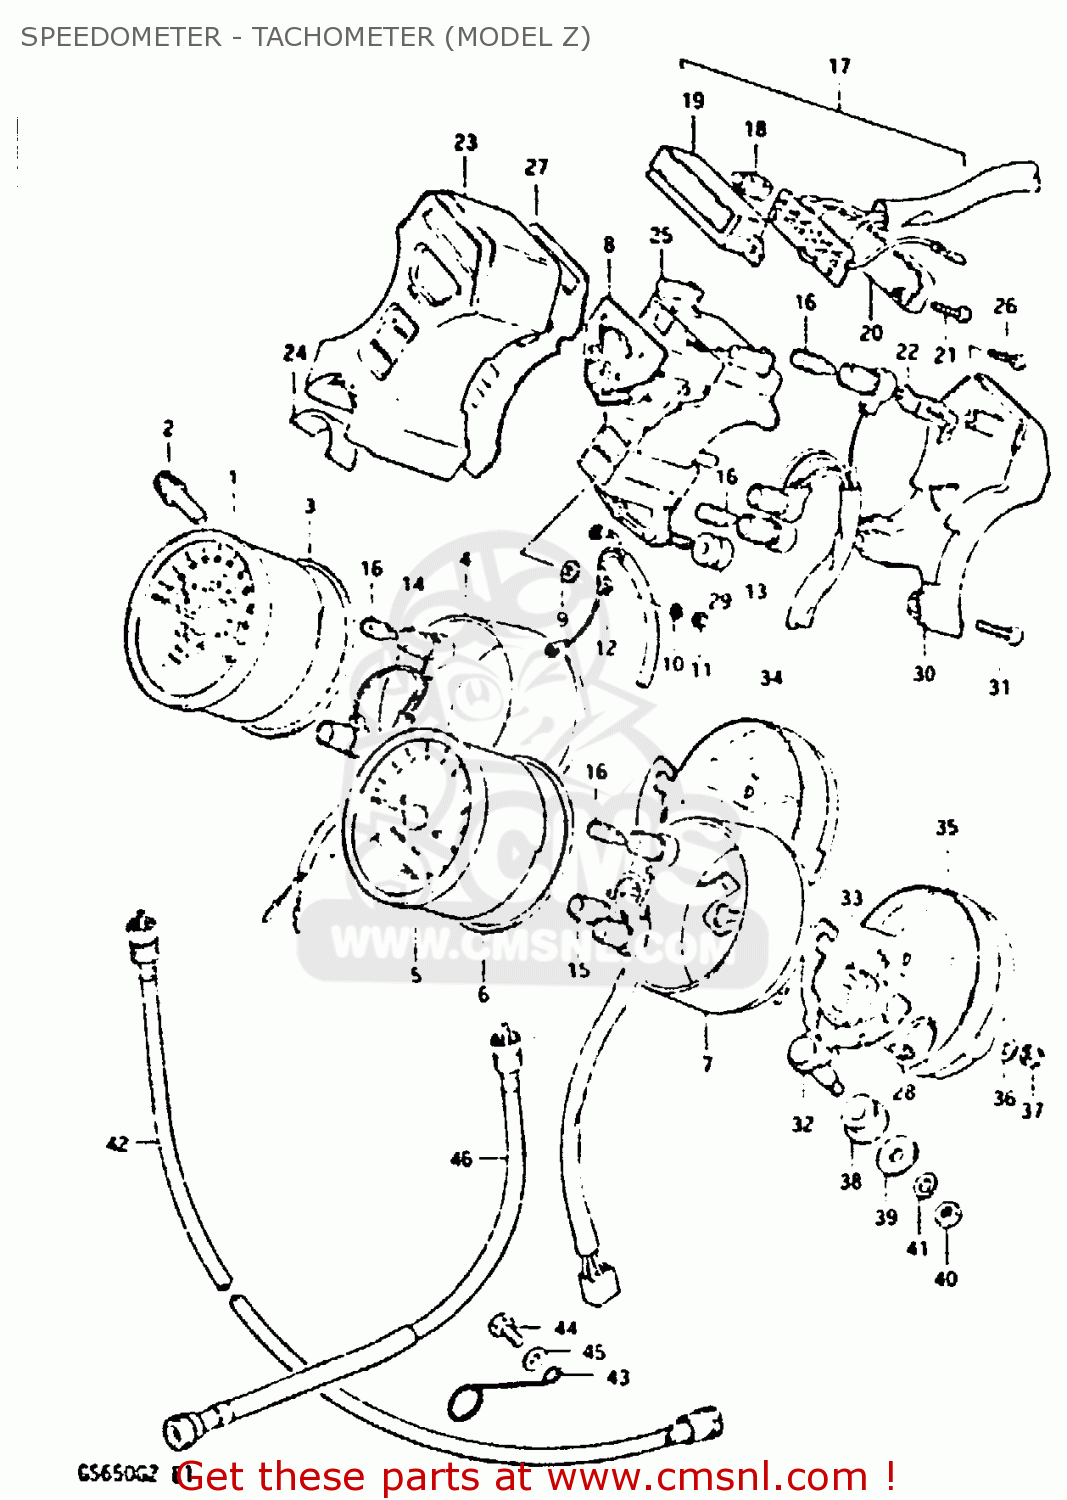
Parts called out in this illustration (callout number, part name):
1	SPEEDOMETER (MILE/KILO)
2	KNOB
3	CUSHION,SPEEDOMETER
4	COVER,SPEEDOMETER
5	TACHOMETER
6	CUSHION,SPEEDOMETER
7	COVER,TACHOMETER
8	METER,FUEL
9	WASHER,FUEL METER
10	LOCK WASHER
11	NUT
12	LEAD WIRE, FUELMETER
13	SOCKET
14	SOCKET,METER
15	SOCKET,TACHOMETER
16	BULB(12V3.4W,T10)
17	INDICATOR ASSEMBLY,GEAR POSITION
18	BULB(14V1.12W)
19	CASE,GEAR INDICATOR
20	COVER,LWR
21	SCREW,GEAR INDICATOR
22	CLAMP,CORD
23	CASE,PILOT BOX
24	SEAL,IGNITION SWITCH
25	CASE,PILOT BOX,INNER
26	SCREW,INDICATOR
27	PLATE,PILOT BOX
28	CUSHION
29	CUSHION,PILOT BOX
30	COVER,PILOT BOX,UNDER
31	SCREW
32	BRACKET
33	CUSHION,METER
34	COVER,SPEEDOMETER,UNDER
35	COVER,TACHOMETER,UNDER
36	WASHER
37	NUT
38	CUSHION,METER BRACKET
39	WASHER (8.5X29X1.6)
40	NUT
41	LOCK WASHER
42	CABLE ASSEMBLY,SPEEDOMETER
43	CLAMP,SPEEDOMETER CABLE
44	BOLT, UPPER
45	WASHER
46	CABLE ASSEMBLY,TACHOMETER
